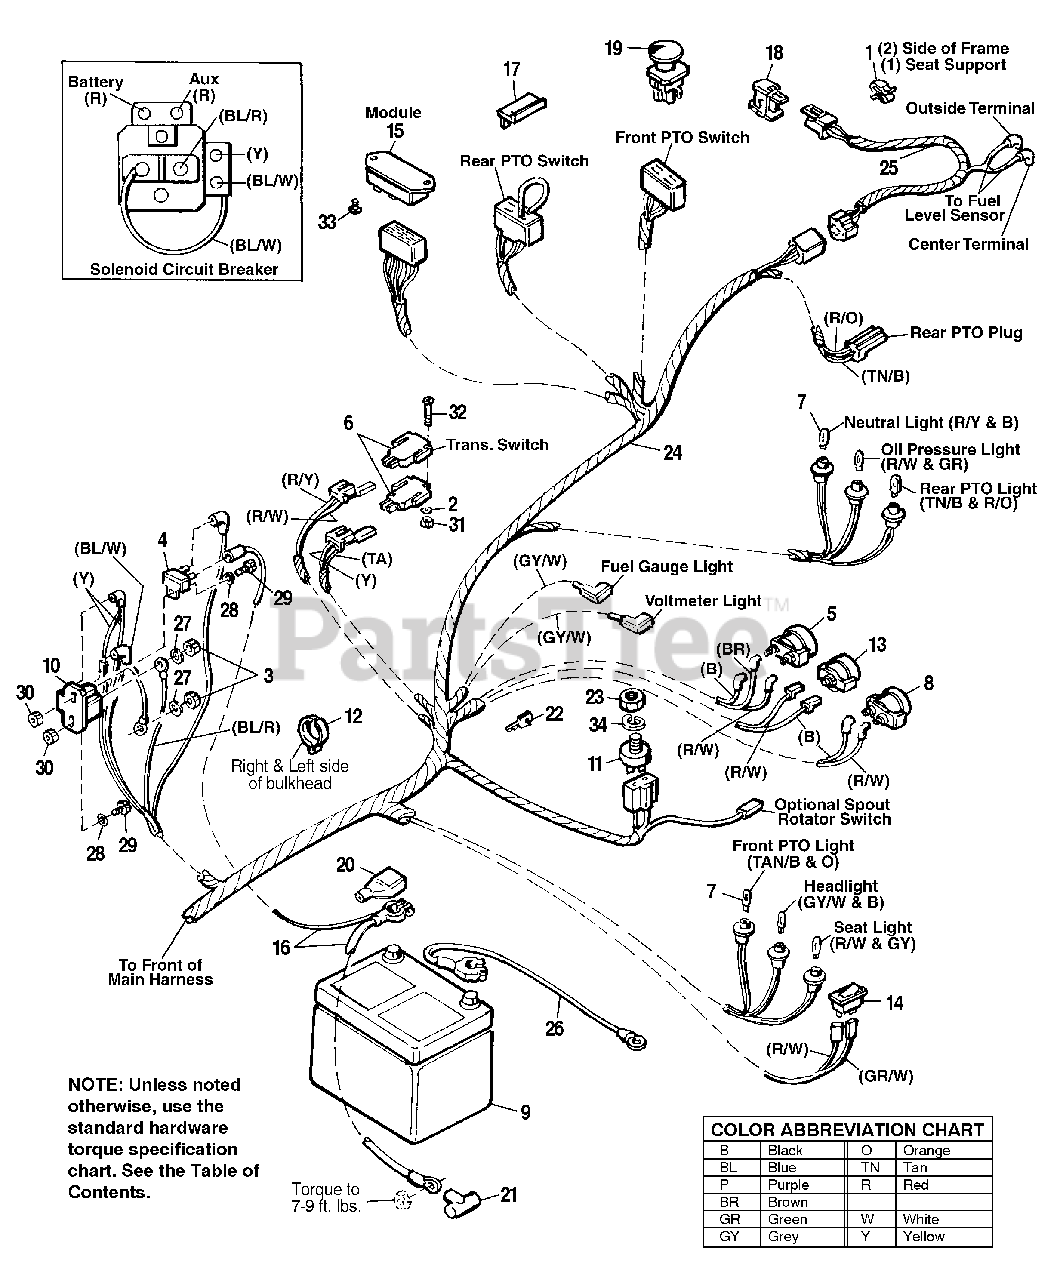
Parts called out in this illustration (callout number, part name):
1	CLIP, Tinnerman
3	NUT, Hex, Jam, 5/16-24, Zinc Plated
4	BREAKER, Circuit
5	GAUGE, Fuel
6	SWITCH, Interlock (Under Dash) Shift Lever
7	LAMP, Indicator
8	VOLTMETER
9	BATTERY (400 AMP Cold Crank Rating)
10	SOLENOID (12 Volt DC)
11	IGNITION SWITCH KIT,
14	TOGGLE SWITCH, Headlight
15	INTERLOCK MODULE
16	CABLE (Battery to Solenoid)
18	SAFETY SWITCH (Seat), Operator Present
19	SWITCH ASSY., PTO
20	PROTECTOR, Battery (Red)
21	COVER, Terminal
22	IGNITION KEY
23	NUT, Hex, Flange, 5/8
24	WIRING HARNESS (Main)
25	HARNESS, Rear
26	CABLE (Battery to Ground)
27	LOCKWASHER, 5/16, Zinc Plated
28	WASHER, Plain, 1/4
29	CAPSCREW, Hex Hd., 1/4-20 x 3/4
30	NUT, Hex, Flange, Whizlock, 1/4-20
31	NUT, Hex, #5-40
32	SCREW, #5-24 x 1-1/2
33	SCREW, Hex, Washer Hd., Plastite, #8-16 x 1/2
34	WASHER, Internal Tooth, 5/8
